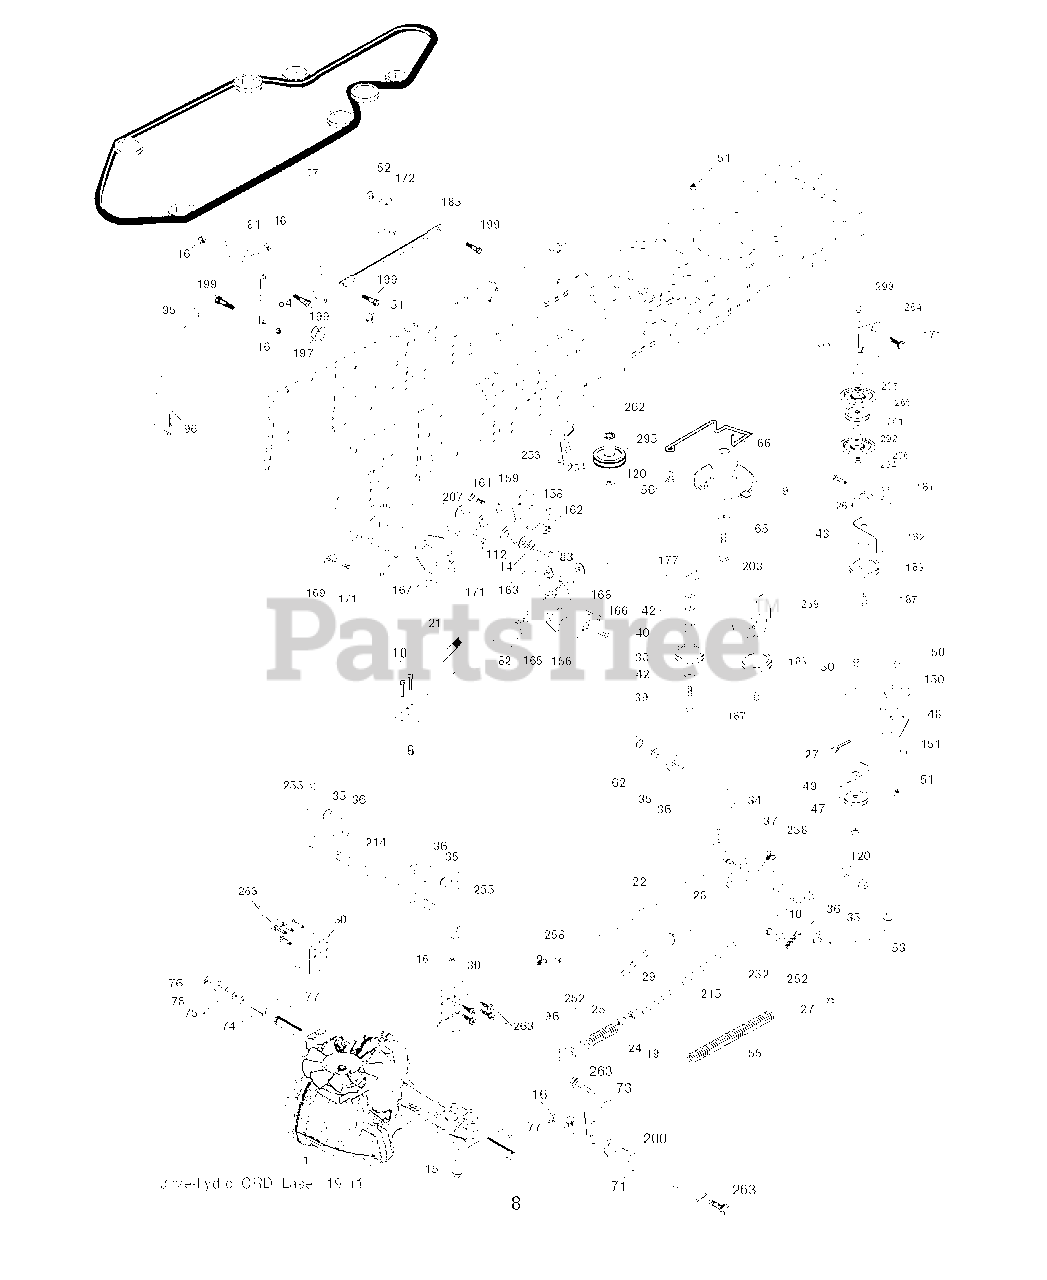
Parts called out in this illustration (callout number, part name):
8	ROD SHIFT FENDER ADJUST LT
10	PIN COTTER
14	LOCKWASHER
15	BOLT HEX 5/16-18 GR 5
16	NUT.71038.31-18.HEX.NYLOCK
19	NUT
21	PISTOL KNOB
24	NUT
27	COTTER PIN
28	ROD, PARKING BRAKE
29	PLUNGER CAP
30	BRKT, TRNSXLE MNT 20"
34	SHAFT, FOOT PEDAL
35	BEARING.NYLON
36	WASHER LT
37	DRIVE PIN
38	PULLEY.FLAT
42	WASHER
47	IDLER PULLEY
48	BELLCRANK, CLUTCH
49	RETAIN BELT
50	BOLT.3/8-16X1.50
51	LOCKNUT
52	LOCKNUT
53	LINK.CLUTCH.7.66.2005
55	SPRING, RETURN LT
56	SCREW.3/8-16
62	PEDAL COVER T
65	LOCKWASHER
66	KEEPER BELT ENGINE
71	STRAP TORQUE LH HYDRO
73	STRAP TORQUE RH HYDRO
74	SPACER AXLE
76	E-RING LT
77	SQUARE KEY
81	SHAFT ASSY
82	SHIFT SPRING
83	WASHER
96	RETAINER M
112	WASHER LT
120	NUT LOCK FLG 3/8-16 UNC
150	BUSHING.BELLCRANK.GRD.DR
151	WASHER 12/32X2X10GA
156	WASHER.SRRTD.5/16
158	BRACKET
159	HUB.SHIFT
161	BOLT
162	NUT.CROWNLOCK.1/4
165	RP BRACKET
167	BRACKET
168	BOLT.SHOULDER.5/16-18X
169	PLATE.FASTENING.CROSS.SHAFT
187	BOLT.5/16-18X1.25
197	NYLINER SNAP 5/8" ID
199	BOLT SHOULDER 5/16-18 UNC
200	BOLT
207	WASHER NYL
254	SCREW 3/8-16X1
258	CLIP RETAINER
261	FLAT IDLER PULLEY
263	SCREW, 3/8-16X3/4
294	NUT, HEX 3/8-16
295	PULLEY IDLER COMPOSITE
